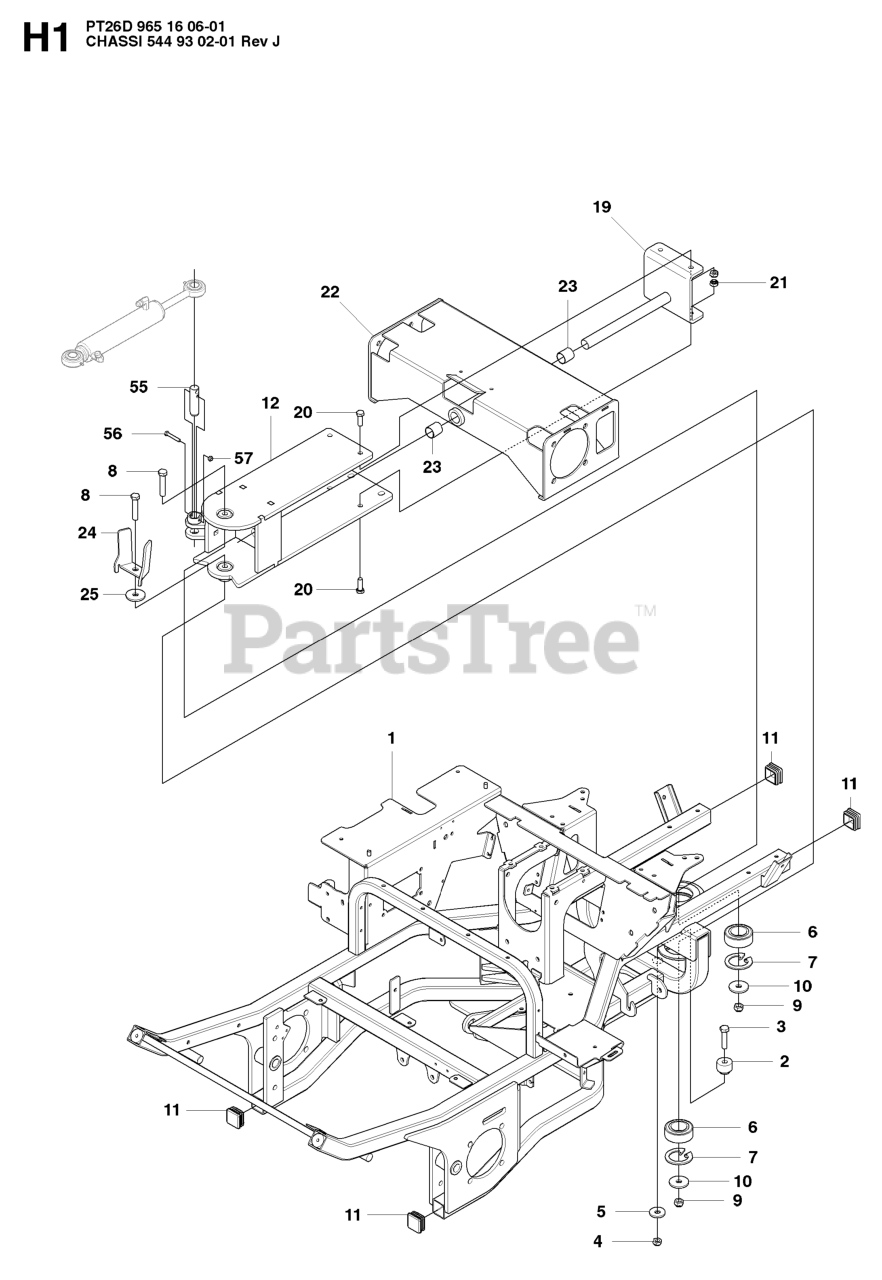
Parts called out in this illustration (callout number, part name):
2	STOP SLEEVE STEERING STOP
12	FRAME REAR
15	WASHER
19	SWING AXLE
21	NUT
23	BUSHING
24	GUIDE PLATE HYDRAULIC HOSES
57	LOCKNUT M6
